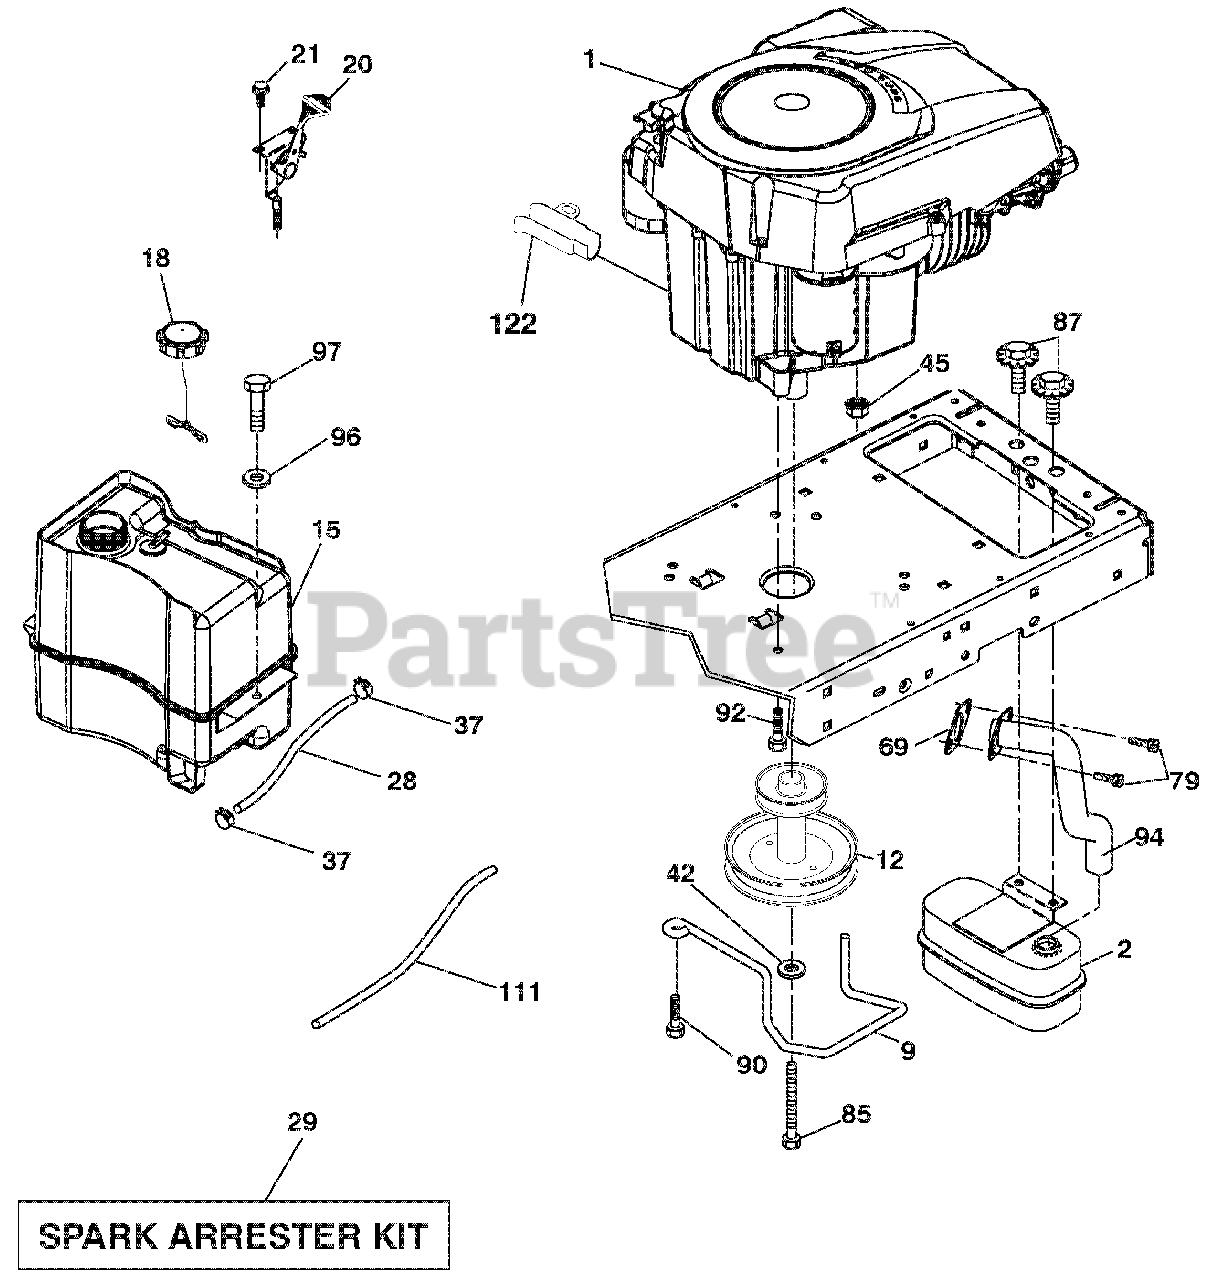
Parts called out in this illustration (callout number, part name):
1	ENGINE KOHLER MODEL NO. SV591-3214 (585954501)(ORDER PARTS FROM ENGINE MANUFACTURER.)
2	MUFFLER
9	KEEPER BELT ENGINE
12	ENGINE PULLEY
15	TANK.FUEL.2.5.GAL.
18	CAP.FUEL
20	CONTROL THROTTLE/CHOKE
28	LINE.FUEL.20"
29	KIT.SPARK ARRESTOR(392390 B&S)
37	CLAMP.HOSE.BLK.
42	WASHER.LOCK.HVY HLCL.SPR.7/16
45	Nut, Keps Hex 1/4-20 unc
69	GASKET.KOHLER.SV.I.
79	SCREW.SOCKET HD.5/16-18 X .75
85	BOLT.HEX.7/16-20X4XGR5-1.5THR.
87	BOLT.5/16-18UNCX3/4 W/SEMS.BLK
90	SCREW.3/8-16X1.SMGML.TAP/R.BLK
92	SCREW.3/8-16X1.SMGML.TAP/R.BLK
94	TUBE.EXHAUST (ENGINE)
96	WASHER.9/32 X 7/8 X 16GA.
97	SCREW.HEXWSH.THDROL.1/4-20X3/4
111	PURGE.LINE.CARB
122	Extension Drain Oil
